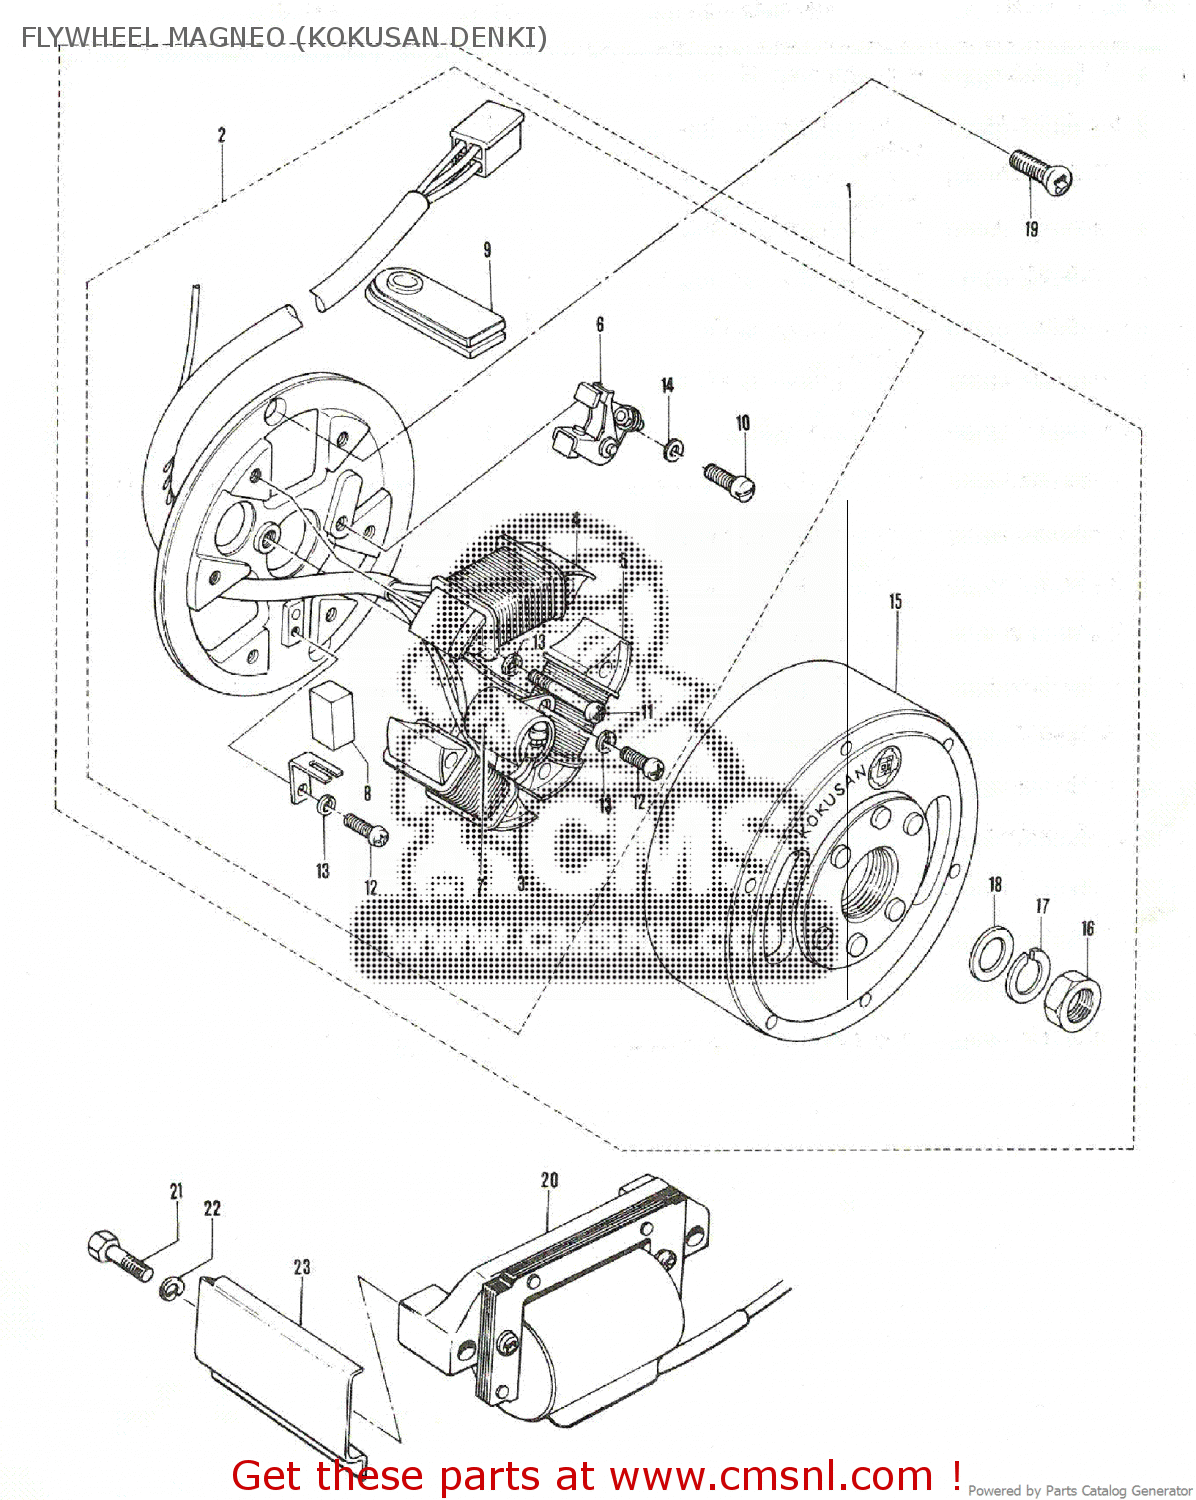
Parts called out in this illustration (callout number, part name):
1	MAGNETO ASSEMBLY
2	STATOR ASSEMBLY
3	COIL
4	COIL
5	COIL,LIGHTING
6	POINT ASSEMBLY,CONTACT
7	CONDENSER
8	FELT,OIL
9	GROMMET
10	SCREW
11	SCREW
12	SCREW
13	LOCK WASHER
14	WASHER
15	ROTOR,FLYWHEEL
16	NUT (10MM)
17	LOCK WASHER
18	WASHER
19	SCREW
20	COIL ASSEMBLY,IGNITION
21	CROSS HEAD SCREW
22	LOCK WASHER
23	IGNITION COIL COVER
